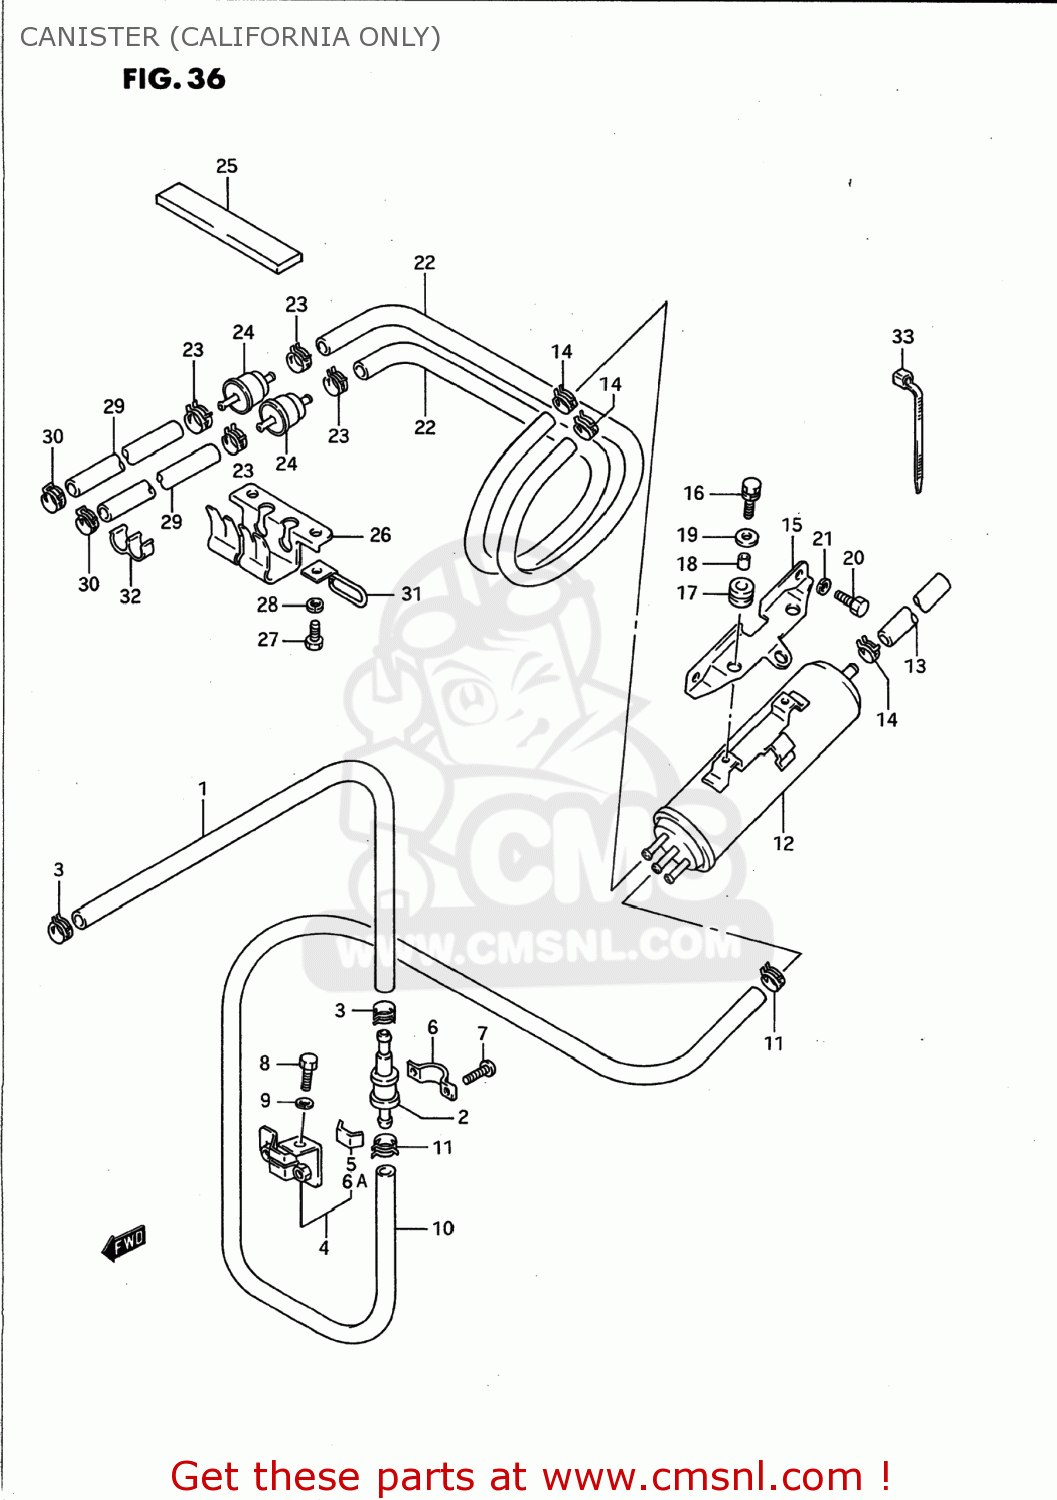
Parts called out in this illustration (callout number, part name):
1	HOSE
2	VALVE,FUEL TANK BREATHER
3	CLIP
4	BRACKET COMP,TANK BREATHER
5	CUSHION
6	PLATE,FUEL TANK BREATHER NO.2
6A	CUSHION
7	SCREW
8	BOLT
9	WASHER,LOCK
10	HOSE,BREATHER VALVE & CANISTER
11	CLIP
12	CANISTER ASSEMBLY,CHARCOAL
13	HOSE (7X12X600)
14	CLIP
15	BRACKET,CANISTER MOUNT
16	BOLT
17	CUSHION
18	SPACER(6.1X9X7.5)
19	WASHER(6,5X22X1.6)
20	BOLT
21	WASHER,LOCK
22	HOSE(5.4X11.4X600)
23	CLIP
24	VALVE,CANISTER PURGE
25	CUSHION,COVER SIDE
26	HOLDER,CPV
27	BOLT
28	WASHER,LOCK
29	HOSE (5.4X11.4X600)
30	CLIP
31	GUIDE,HOSE
32	CLAMP
